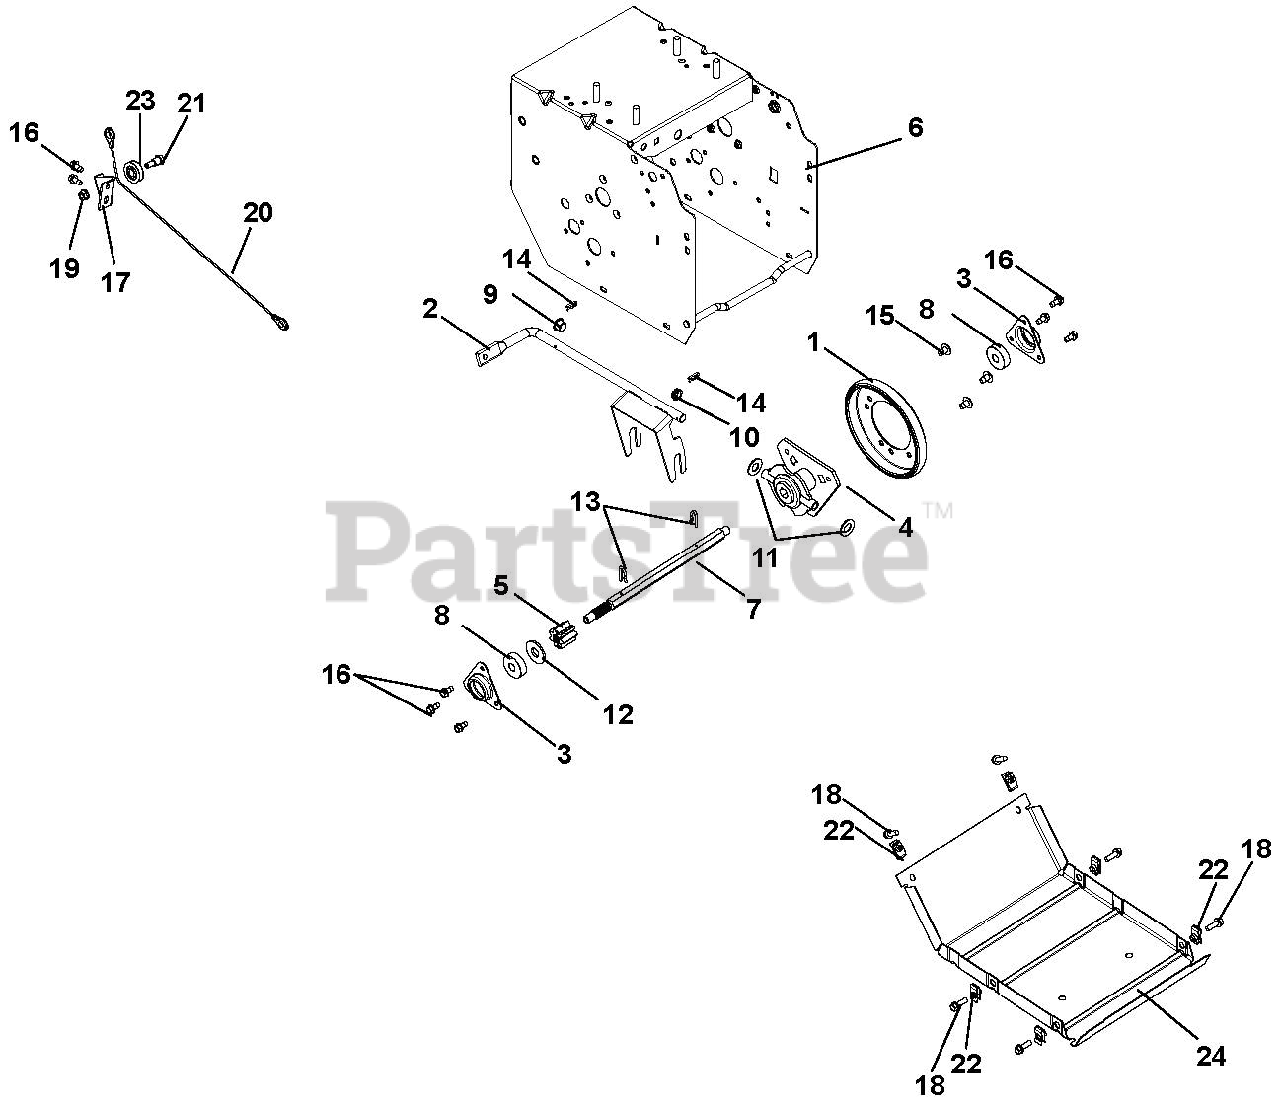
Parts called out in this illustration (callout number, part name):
1	FRICTION, DISC
2	WELDMENT, SHIFT FORK
3	FLANGE, BEARING
4	CARRIER, DRIVE DISK
5	GEAR, PINION, 7 TOOTH W/SPLINE
6	FRAME W/ENGINE BOLT STRAPS
7	SHAFT, HEX W/SPLINE
8	BRG-BALL .437X1.375X.437
9	BUSHING, POLYLINER-.50 SPLIT
10	BUSHING, POLYLINER-.50 SNAPIN
11	WSHR-FL-STL .505X1.00X.062YWZC
12	@WSHR-FL-STL.563X1.38X.109YWZC
13	PIN, SPRING CLIP
14	CLIP, SPRING
15	SCR-TAP SERRDHDTX .31-18X.50BP
16	SCR-TAP .25-20X.50 HWH TR YWZ
17	BRACKET, CABLE PULLEY
18	BLT-HEX .25-20X.75 HWH YZ GR5
19	@NUT-LK-CTR-FLG .25-20 YWZC
20	CABLE, LOWER TRACTION (CMPCT)
21	BOLT, SHLDR-.375X.375X.25-20
22	NUT-RTNR .25-20X.56
23	PULLEY, CABLE
24	COVER, BOTTOM
